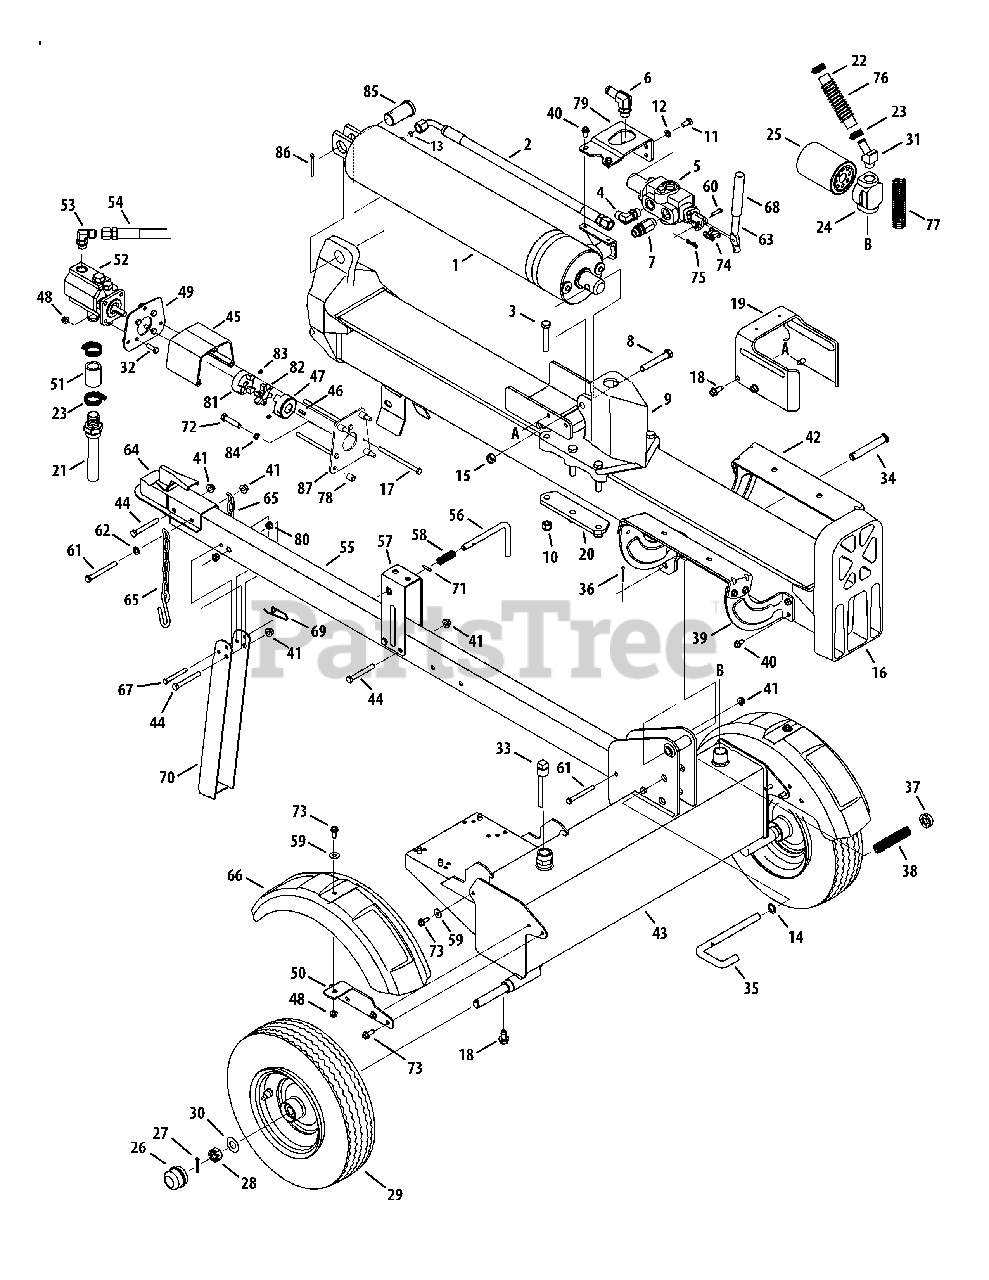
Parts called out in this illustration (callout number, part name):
2	Hydraulic Tube
3	Hex Cap Screw, 1/2-20 x 2.75
4	90 Degree Solid Adapter
5	Control Valve
6	Return Elbow
7	Nipple Pipe, 1/2-14
8	Hex Cap Screw, 1/2-13 x 3.25
9	Wedge Assembly
10	Hex Lock Nut, 1/2-20
11	Hex Cap Screw, 3/8-16 x .75
12	Lock Washer, 3/8
13	O-Ring, .489 ID x .070 Dia.
14	Flat Washer, .635 x.93 x.06
15	Hex Lock Nut, 1/2-13
16	Beam Assembly
17	Hex Screw, 5/16-18 x 4.75
18	Self Tapping Screw, 3/8-16 x 1.0
19	Dislodger Bracket
21	Inlet Filter
22	Return Hose, 3/4 x 44
23	Hose Clamp, 5/8
24	Filter Housing
25	Oil Filter
27	Cotter Pin
28	Slotted Nut, 3/4-16
29	Complete Wheel Assembly
29	Dust Seal
29	Roller Bearing
30	Flat Washer, .760 x 1.500
31	Hydraulic Fitting, 1 1/16 Orb x .75
32	Hex Screw, 5/16-18 x 1.00
33	Vented Dipstick
34	Clevis Pin
36	Cotter Pin
38	Compression Spring
39	Log Tray Bracket
40	Hex Washer Screw, 5/16-18 x .750
41	Flange Lock Nut, 3/8-16
43	Frame Assembly
44	Hex Bolt, 3/8-16 x 3
45	Coupling Shield
46	Square Key, 3/16 x .75
47	Coupling, .875
48	Flange Lock Nut, 5/16-18
49	Rear Coupling Support Bracket
50	Fender Mounting Bracket
53	Hydraulic Fitting, 7/8 Orb x .8125
54	High Pressure Hydraulic Hose
55	Tongue Assembly
56	Latch Rod
58	Compression Spring
59	Flat Washer
60	Clevis Pin
61	Hex Cap Screw, 3/8-16 x 3.50
62	Flat Washer, .375 x.738 x.063
63	Hydraulic Valve Control
64	Hitch Coupling Assembly
67	Clevis Pin
69	Spring Pin
71	Spiral Pin
72	Hex Cap Screw, 5/16-24 x .75
73	Self-Tapping Screw, 5/16-18 x 1.00
74	Valve Handle Link
75	Cotter Pin, Bow Tie
76	Hose Guard, 44"
77	Hose Guard, 48"
78	Spacer, .385 x .623 x .75 LG
79	Outer Valve Bracket
80	Plastic Bushing, .380 ID
81	Coupling, .500
82	Spider Bushing
83	Set Screws
84	Lock Washer, 5/16
85	Clevis Pin, 1.25 x 2.50
86	Cotter Pin, 3/16 x 2
87	Front Coupling Support Bracket
